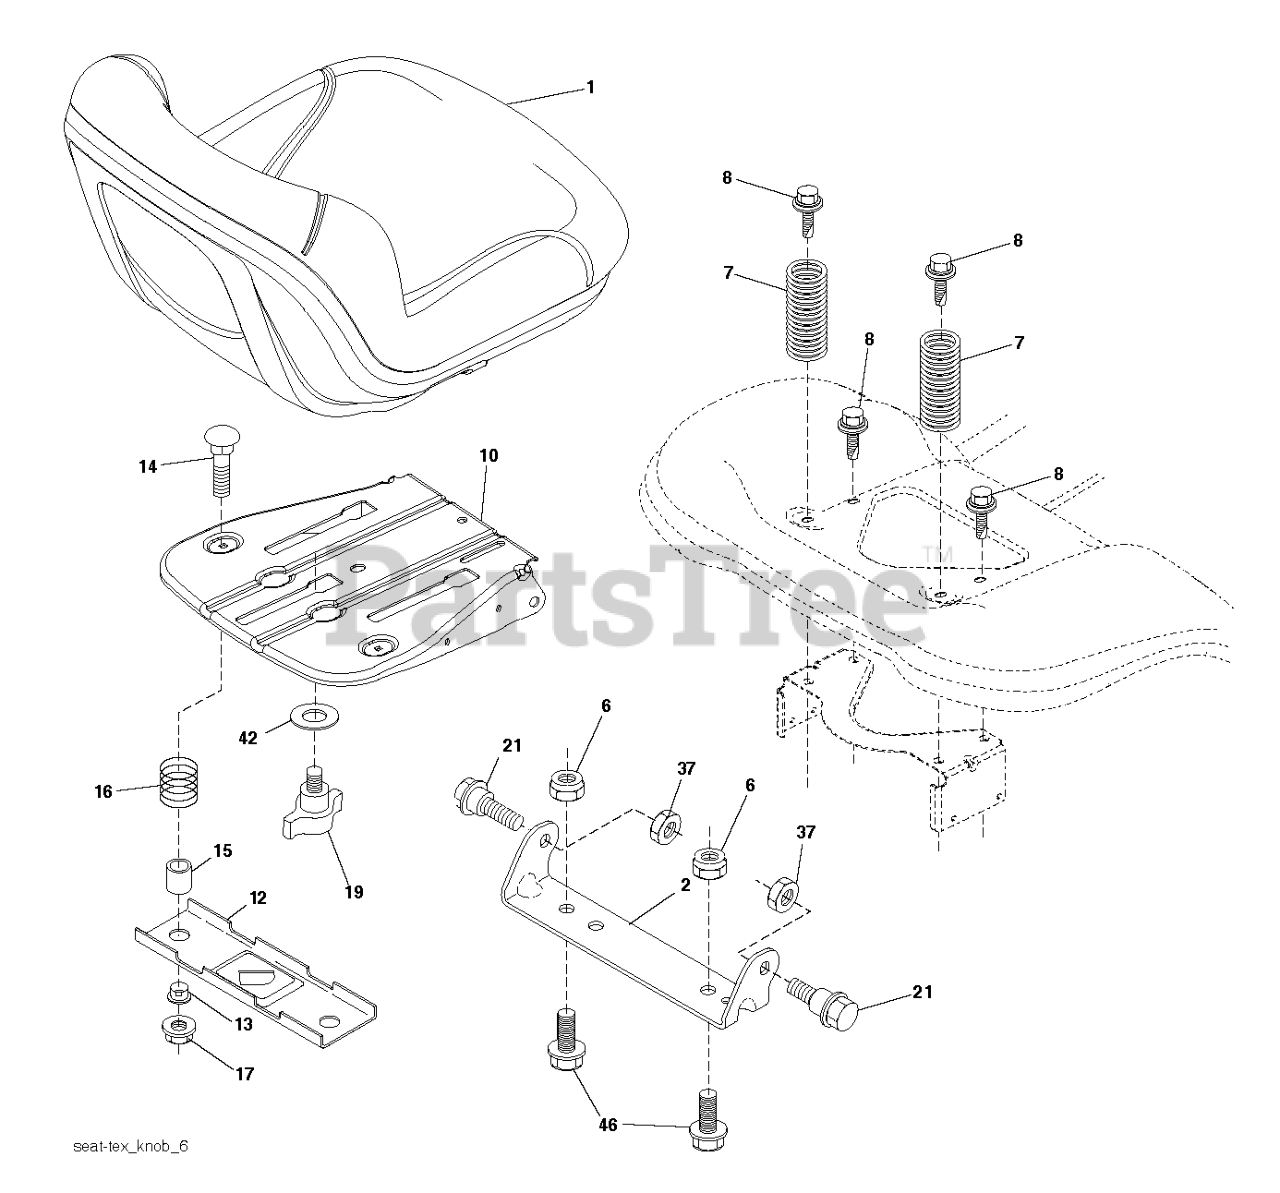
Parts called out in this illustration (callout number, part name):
1	SEAT.TP150.BLK.PPRO.KB/SL
2	BRKT.PIVOT.FENDER
6	Nut, Lock, Hex with Wsh Insert 3/8-16 UNC (AYP part number)
7	SPRING.COMPRESSION.SEAT.BLACK
8	BOLT, 5/16-18 X 1 3/4
10	PAN.ASM.SEAT.SHORT.SLD.ADJ.TEX
12	BRKT.MNT.OPC.SW.SEAT.
13	Bushing Snap Blk Nyl 50 Id (AYP part number)
14	BOLT.ROUND.HEAD.SQUARE.NECK
15	Spacer, Split, Large .28 ld. x .96 (AYP part number)
16	Locknut, Hex, Large, Flanged 1/4-20 UNC (AYP part number)
17	Locknut, Hex, Large, Flanged 1/4-20 UNC (AYP part number)
19	KNOB.SEAT.ADJ.
21	BOLT.5/16-18X5/8.SHOULDER
37	Locknut, Hex, with Washer Insert 5/16-18 (AYP part number)
42	WASHER.CUP.SEAT.
46	BOLT.3/8-16X1;1.25OD.WSHR.SEMS
